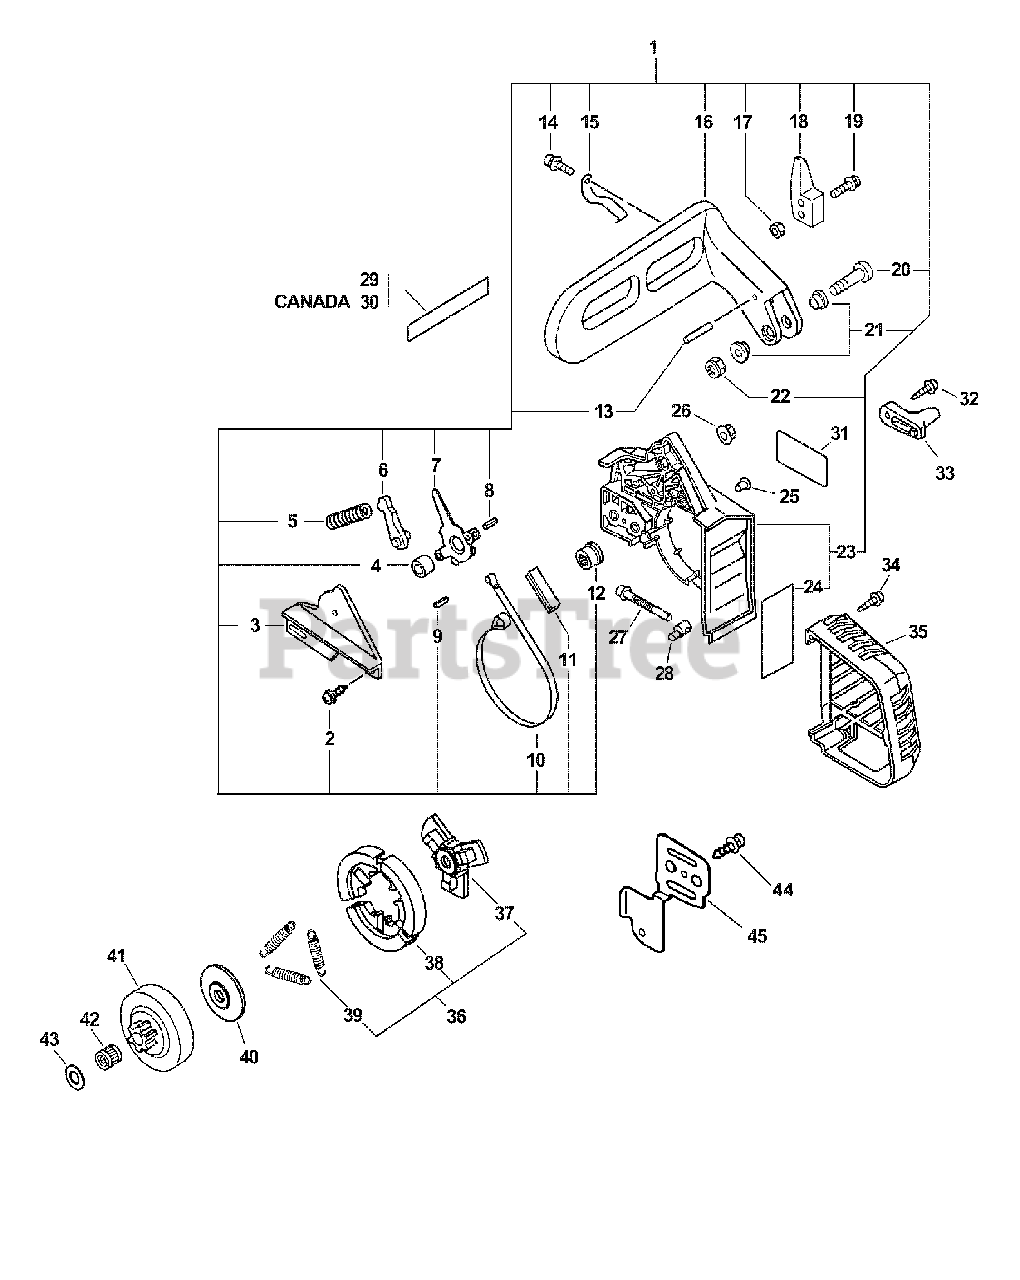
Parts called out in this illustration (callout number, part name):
1	CHAIN BRAKE ASSY
2	SCREW 4×12
3	COVER, BRAKE
4	SPACER 8×12×9
5	SPRING, COMPRESSION
6	STOPPER, BRAKE
7	LEVER, BRAKE
8	PIN, SPRING 4×8.8
9	PIN, SPRING 2.5×12
10	BAND, BRAKE
11	SEAL, BRAKE
12	ADJUSTER, BRAKE
13	ROLLER 4×23.8
14	SCREW 4×10
15	SPRING, FLAT
16	LEVER, BRAKE
18	WEIGHT, BRAKE
19	SCREW 4×22
20	SCREW 5×32
21	COLLAR 5.3×10×13×L5
22	NUT, LOCK M5
23	GUARD, SPROCKET - GRAY
24	SHIELD, HEAT 35×60×0.10
26	NUT, FLANGE M6
28	TENSIONER, CHAIN
29	LABEL, BAR & CHAIN
30	LABEL, BAR & CHAIN
31	LABEL, MODEL
32	SCREW, TAPPING 5×20
33	CHAIN CATCHER
34	SCREW, TAPPING 5×20
35	COVER, MUFFLER
36	CLUTCH ASSY
37	HUB, CLUTCH
38	SHOE SET, CLUTCH (3PCS)
39	SPRING, CLUTCH
40	PLATE, CLUTCH
41	DRUM, CLUTCH 3/8"
42	BEARING, NEEDLE 10×13×10
43	WASHER 10.2×24.5×1.2
44	SCREW 4×10
45	PLATE, GUIDE
